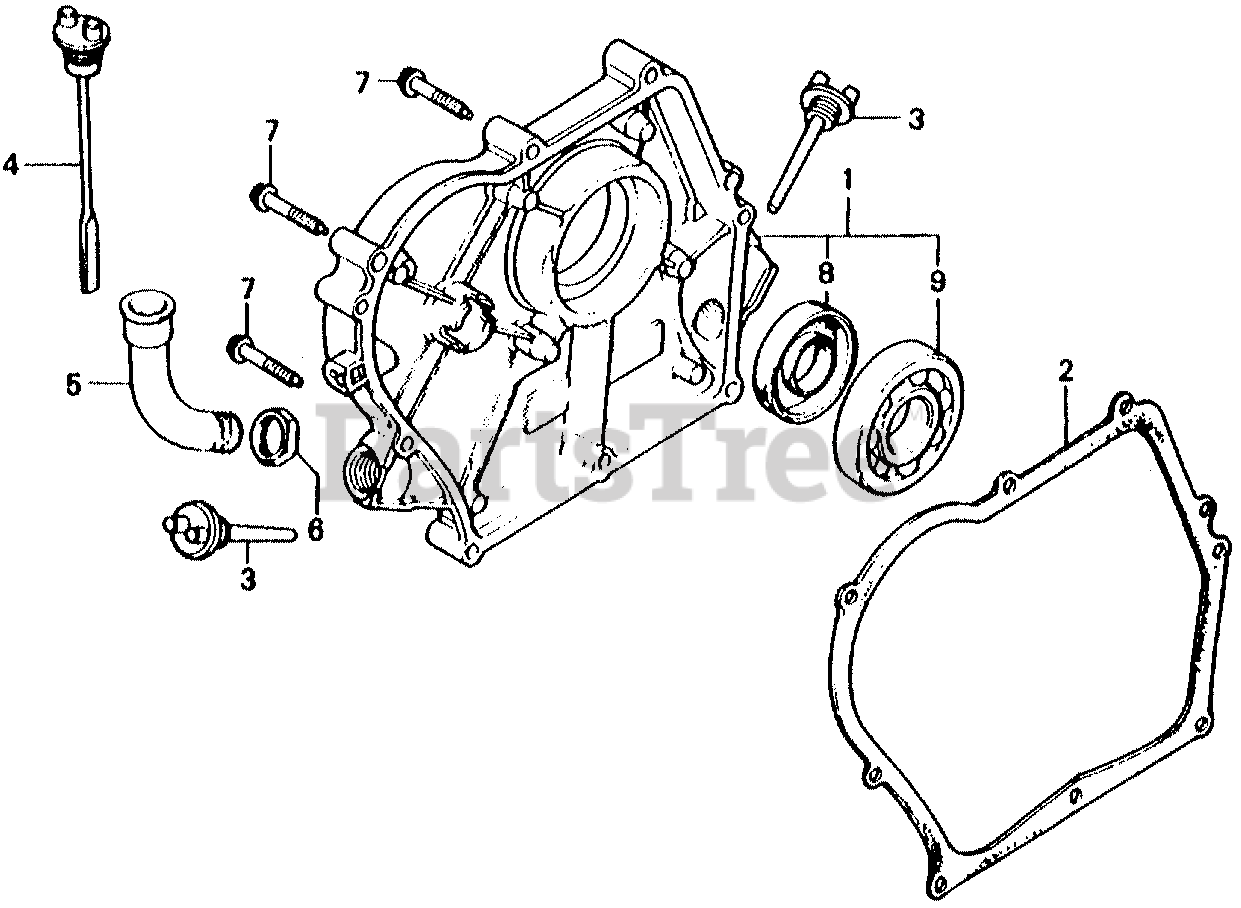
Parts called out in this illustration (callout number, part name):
1	COVER ASSY., CRANKCASE (U-TYPE)
2	GASKET, COVER
3	CAP, OIL
4	CAP, OIL
5	PIPE, OIL
6	NUT, OIL FILLER
7	BOLT, FLANGE (6X32)
8	OIL SEAL (25X41X6)
9	BEARING, RADIAL BALL (6205)
